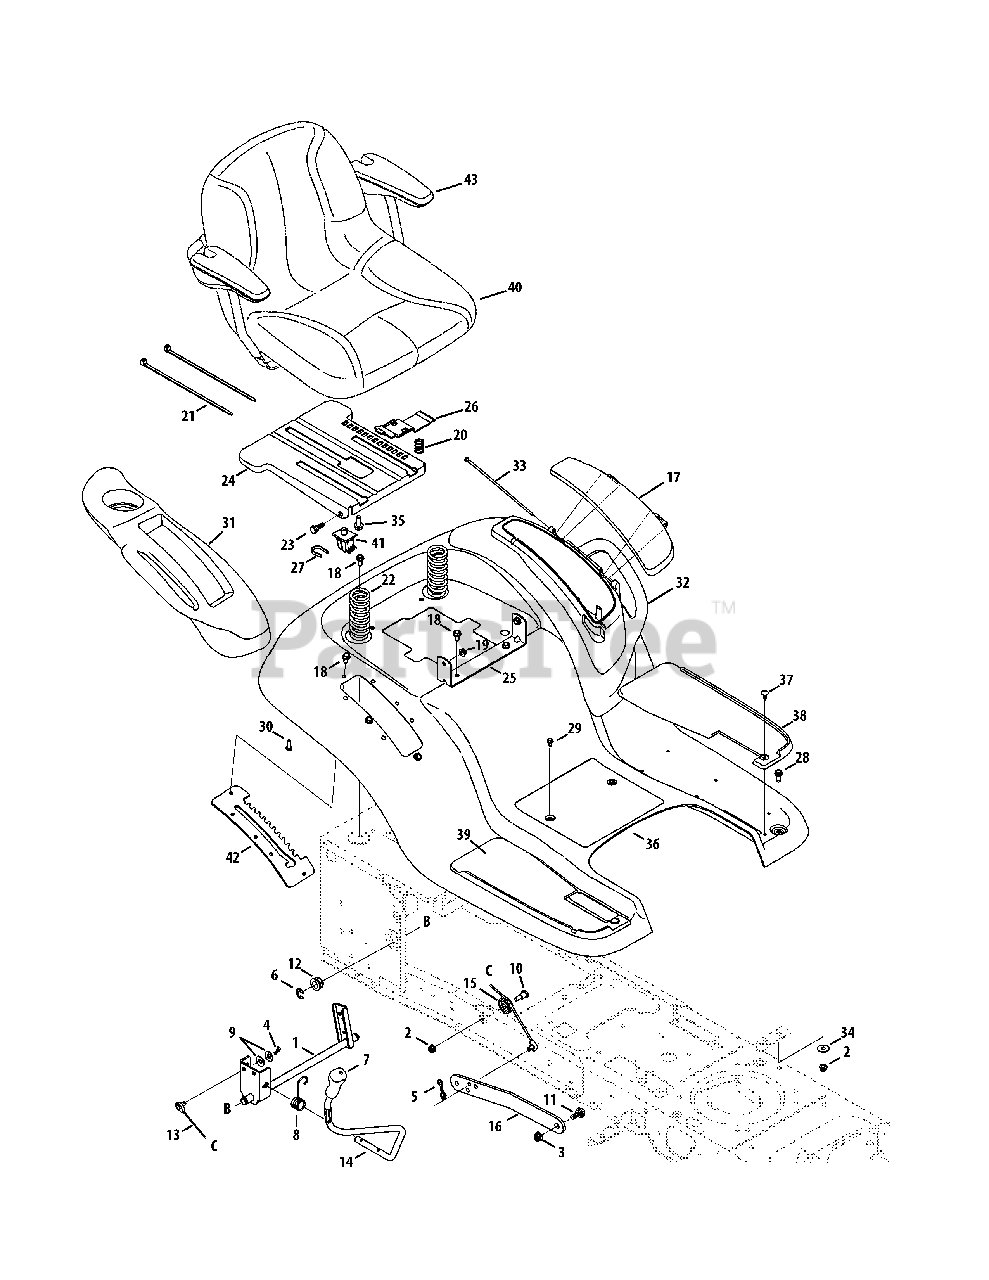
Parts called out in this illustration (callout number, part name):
1	Shaft Ass’y, Lift
2	Nut, Flange Lock, 5/16-18, Grf
3	Nut, Flange Lock, 3/8-16, Grf
4	Pin, Cotter, .072 Dia. x 1.13
5	Pin, Cotter, Bow-Tie 72
6	Ring, E Type, .625 Dia. Shaft
7	Grip, Handle, Cub, .50 ID
8	Spring, Torsion
9	Washer, Spring, .401 x .870 x .063
10	Screw, Shoulder, .437 x .470, 5/16-18
11	Bolt, Shoulder, .50, 3/8-16
12	Bearing, Hex Flange
13	Cable, Lift, 16.16
14	Handle, Lift,
15	Pulley, Roller, Cable
17	Door, Cover, Fender
18	Screw, Self-tapping, 5/16-18, .750,
19	Nut, Flange Lock, 5/16-18, Gr5, Sd Lk
20	Spring, Compr’, .68 x 1.065 x .055
21	Cable, Tie, 3/16 x .05 x 7.4
22	Spring, Comprs, 1.50 x 3.90 x .200
23	Screw, Shoulder, .437 x .268, 5/16-18
24	Bracket, Mounting, Seat
25	Bracket, Pivot, Seat
26	Lever, Seat Adjustment
27	Clip, Retaining, Switch
28	Hex Screw, 5/16-18, .75, Gr5, Std
29	Screw, Self-tapping, 1/4-20, 0.500,
30	Screw, HL, 1/4-15, 0.750,
31	Cover, Fender, RH
32	Cover, Fender, LH
34	Washer, Flat .344 x 1.00 x .063
35	Hex Flange Screw, 3/8/16, .875, Gr5
36	Fender, Cub Hydro
37	Clip, Ratchet, .250 Dia
38	Pad, Foot, LH
39	Pad, Foot, RH
40	Seat, High Back Cloth w/o Arm Rest
41	Switch, Seat
42	Bracket, Lift
43	Arm Rest Kit
